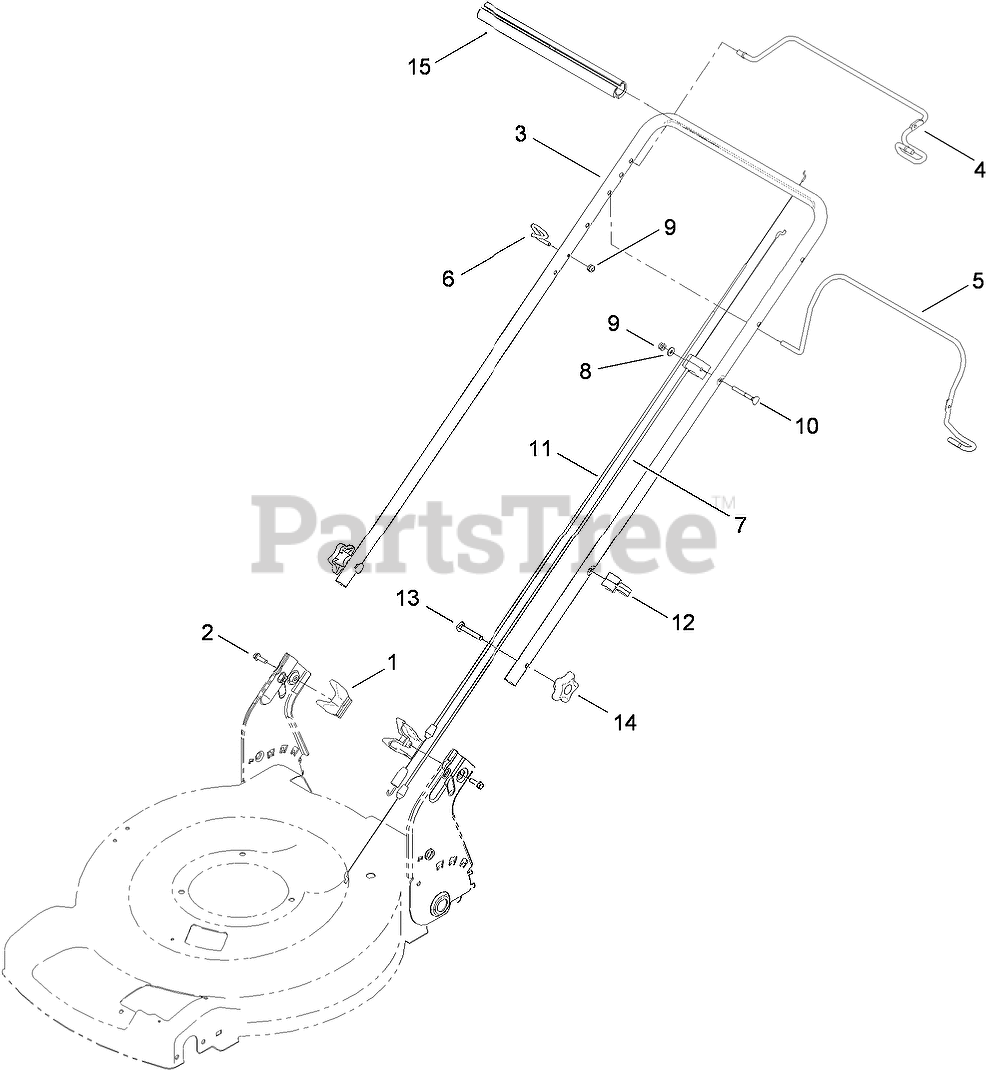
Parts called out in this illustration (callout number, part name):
1	ANCHOR-BAG
2	SCREW-HWH
4	BAIL-TRACTION
5	BAIL-BRAKE
6	GUIDE-ROPE
7	CABLE-BRAKE
8	WASHER-FLAT
9	NUT-LOCK, NI
10	SCREW-HANDLE
11	CABLE-TRACTION
12	GUIDE-CABLE
13	Screw-CARR
14	KNOB-HANDLE
15	GRIP-HANDLE, COMFORT
